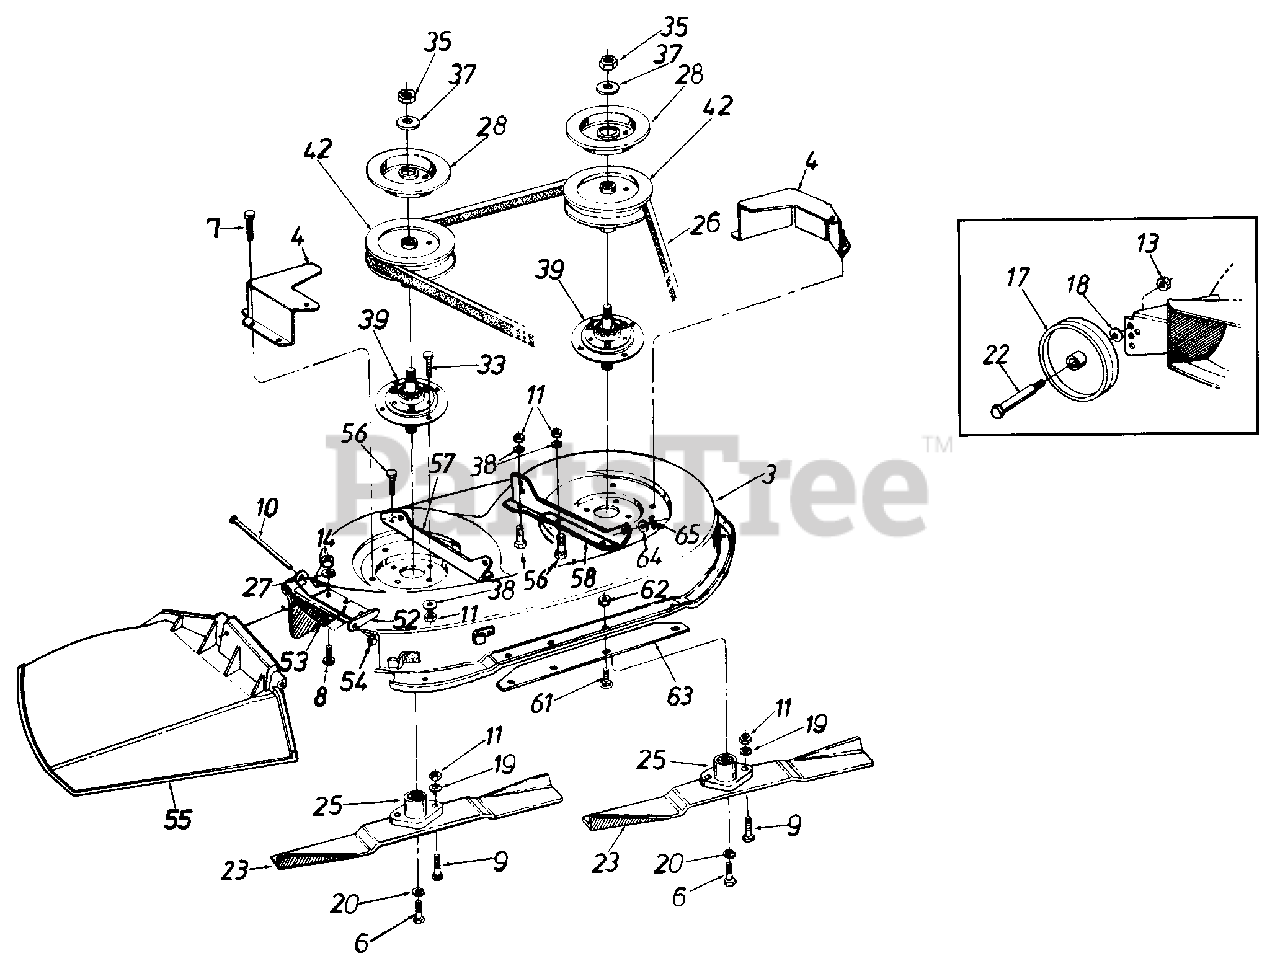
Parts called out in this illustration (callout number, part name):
3	38" Deck Ass'y. w/o Deck Wheels
6	Hex Bolt 3/8-24 x 1.0" Lg.
7	Hex Wash. Hd. TT-Tap Scr. 1/4-20 Thd. (38" Deck)
8	Hex Bolt 1/4-20 x .62" Lg. (38" Deck)
9	Hex Bolt Special 5/16-24 x 1.0"
10	Hinge Pin
11	Hex Nut 5/16-24 Thd.
13	Hex Top L-Nut 3/8-16 Thd.
14	Hex Nut 1/4-20 Thd.
17	Deck Wheel - 5"
18	Bell-Wash. .40" I.D. x .88" O.D.
19	L-Wash. 5/16" I.D.
20	L-Wash. 3/8" I.D.-H.D.
22	Shld. Bolt .498" Dia. x 1.53"
23	High-Lift Blade (38" Deck)
25	Blade Adapter
26	"V"-Belt (38" Deck)
27	Bell-Wash. 1/4" I.D.
28	Brake Disc
33	Hex Bolt 5/16-24 x .75" Lg. (38" Deck)
35	Hex Jam Nut 5/8-18 Thd.
37	L-Wash. 5/8" I.D.
38	Bell-Wash. .345" I.D. x .88" O.D.
39	Blade Spindle Ass'y. Comp.
42	5" Dia. Pulley
52	Hinge Mtg. Brkt.
53	Torsion Spring
54	Push Nut
55	Chute Ass'y. Comp.
56	Hex Bolt 5/16-24 x .75" Lg.
62	Hex Sems Nut 1/4-20 Thd.
65	Hairpin Clip 3/8" Dia.
